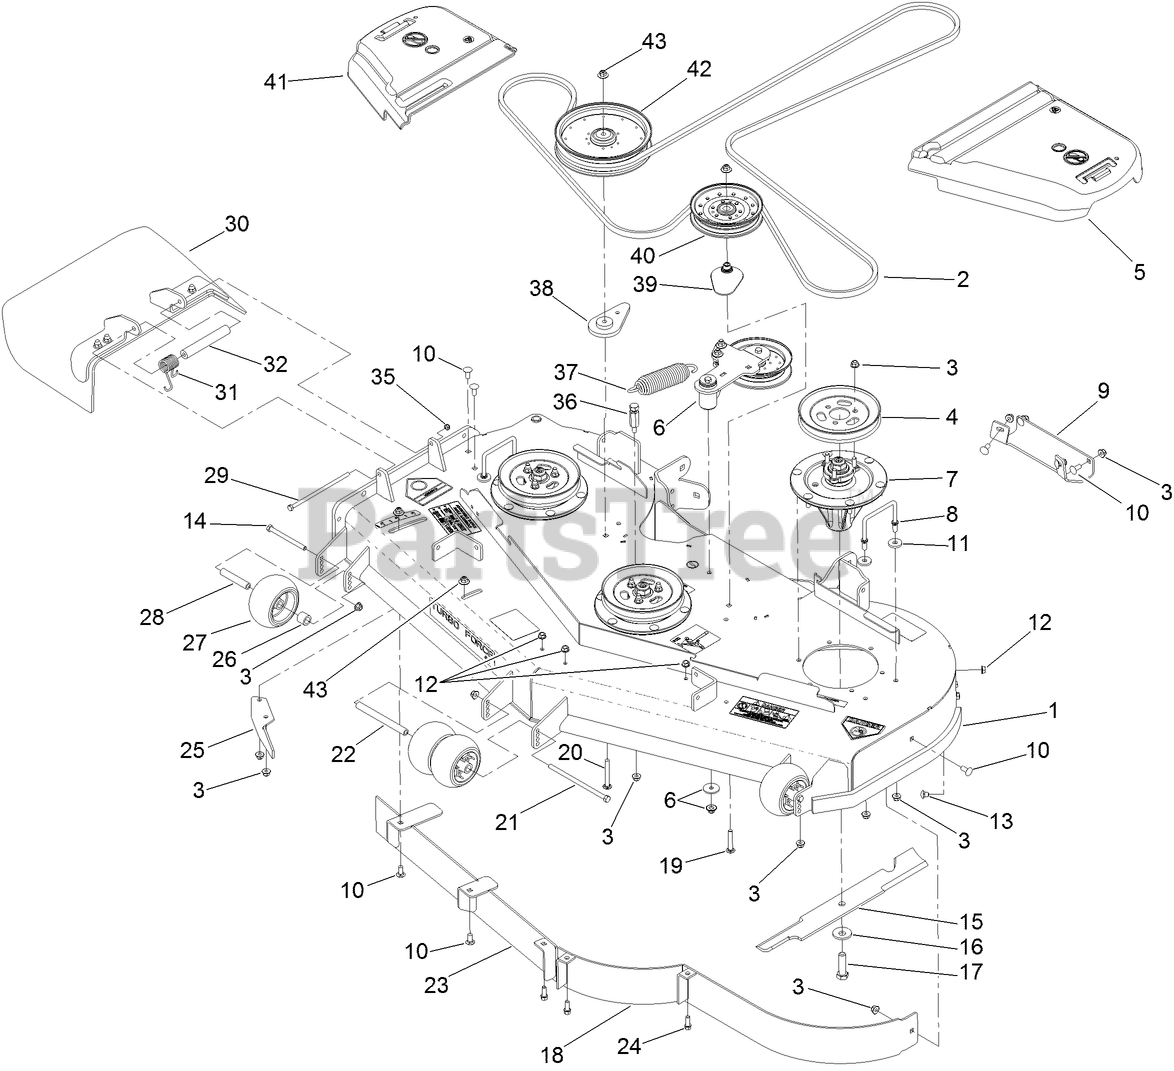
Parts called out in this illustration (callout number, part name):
1	DECK DECAL ASM
2	BELT-V
3	NUT-HF, NI
4	Pulley
5	COVER-BELT, LH
6	IDLER ARM ASM
7	SPINDLE ASM
8	WIREFORM-COVER
9	Plate-Skid
10	SCREW-CARR
11	WASHER
12	NUT-HHF, WHIZ
13	SCREW-CARR
14	SCREW-HH
15	BLADE-HI FLOW
16	Washer-Blade Bolt, Heavy
17	SCREW-BLADE
19	BOLT-CARR, SHORT NECK
20	SCREW-CARR
21	SCREW-HH
22	SPACER-WHEEL
24	SCREW-HWH
25	BAFFLE-DISCHARGE
26	TUBE-SPACER
27	ROLLER-SCALP, ANTI
28	TUBE-SPANNER
29	SCREW-HH
30	RUBBER DEFLECTOR ASM
31	SPRING-TORSION
32	SPACER
35	NUT-LOCK, NI
36	ANCHOR-SPRING, TALL
37	EXTENSION-SPRING
38	SPACER-IDLER
39	SPACER-PULLEY
40	PULLEY-IDLER, FLAT
41	COVER-BELT, RH
42	PULLEY-IDLER
43	NUT-FLANGE, NI
